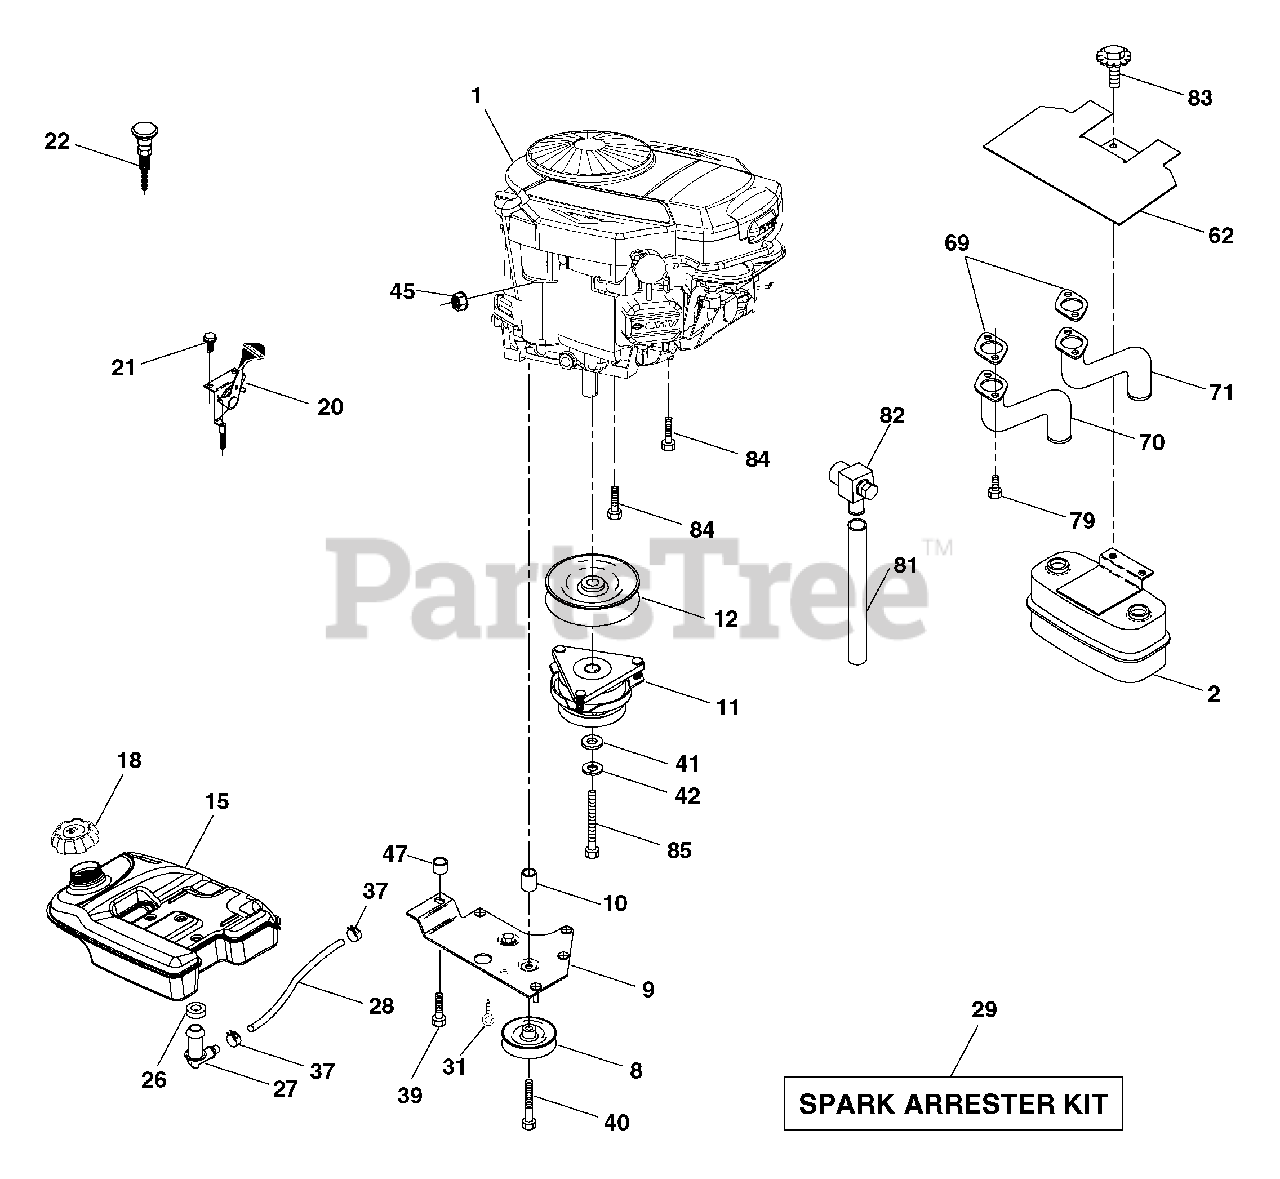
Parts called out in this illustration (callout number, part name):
2	Muffler Side
8	Pulley V-Idler
9	Keeper Asm. Belt Engine VGT
11	Clutch Electric
12	Pulley Engine VGT Elect Clutch
15	Tank Fuel Rear 5.0
18	Cap Fuel
20	Control Throttle
21	Screw 10 x 3/4 Single Lead Hex
22	Control Choke
26	Bushing
27	Stem Tank Fuel
28	Fuel Line
29	Spark Arrester Kit
31	Clip Push-In Hinged
37	Clamp Hose
39	Screw TT 3/8-16 x 2-1/4 unc
40	Screw TT 3/8-16 x 4 unc
41	Washer 1-1/2 OD X 15/32 ID X .250
42	Washer Lock 7/16
45	Nut Keps Hex 1/4-20 UNC
62	Shield Heat Muffler
70	Tube Exhaust LH
71	Tube Exhaust RH
79	Screw Socket Head 5/16-18 x 1
81	Oil Drain Tube
82	Valve Drain Oil
83	Bolt 5/16-18 unc x 1-3/4 W/Sems
84	Screw 3/8-16 x 1-1/2
85	Bolt Hex 7/16-20 x 3.75 Gr. 5
86	Nut Hex Flange Toplock M8-1.25
